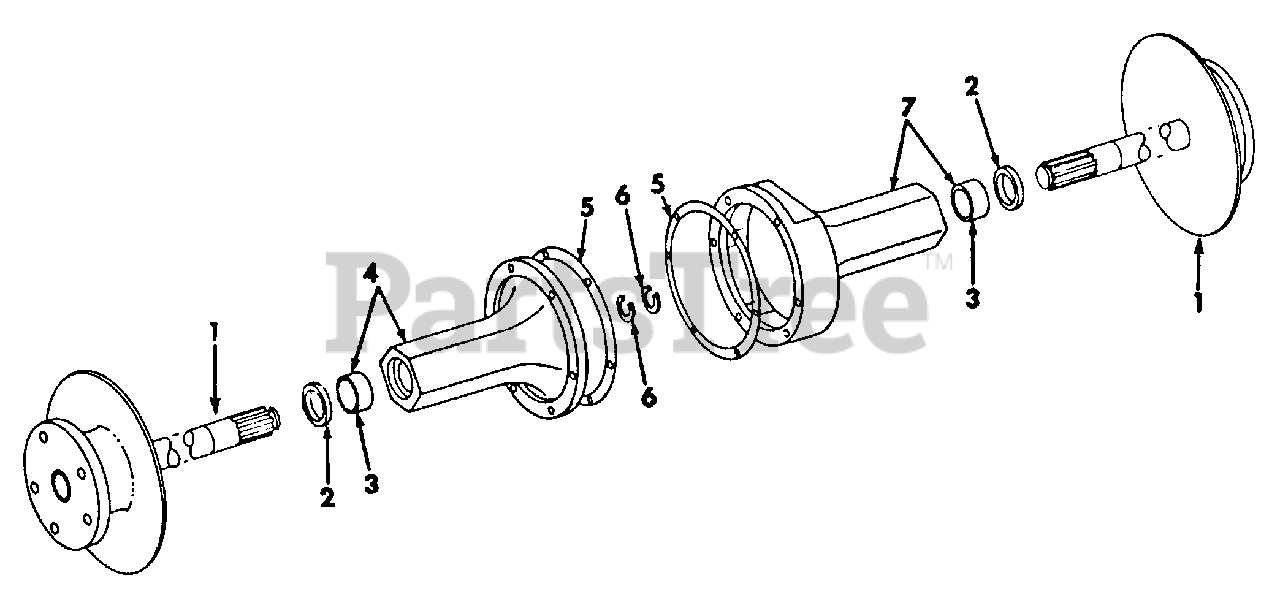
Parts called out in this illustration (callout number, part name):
1	Axle Assy, Rear
2	Seal, Oil
3	Bearing, Needle
4	Carrier Assy, Rear Axle LH
5	Gasket, Carrier
6	Ring, Retaining
7	Carrier Assy, Rear Axle RH
